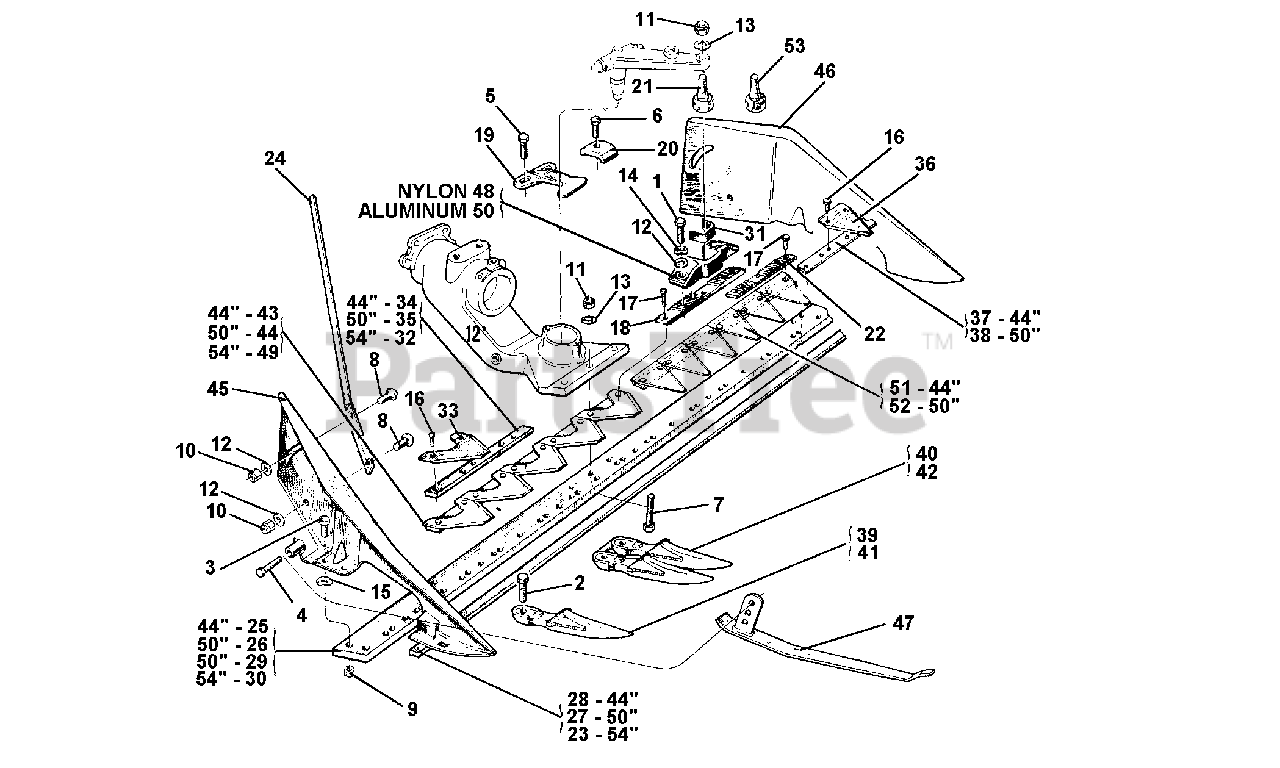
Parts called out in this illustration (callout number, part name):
1	SCREW M8 X 16
2	SCREW TE M10 X 25
3	SCREW TE M10 X 30
4	SCREW TE M10 X 20 UNI 5739-8G
5	SCREW M10 X 30
6	SCREW TE M10 X 35 UNI 5739-8G
10	NUT, SELF LOCKING M8
11	SELF LOCKING NUT
12	WASHER, FLAT 8.4
13	SUPER WASHER 10 DIN 6796
14	WASHER, LOCK 8.4
15	WASHER, LOCK 10.5
16	RIVET 5.3 X 14
17	RIVET TSV 5.3 X 14
18	SUPPORT, BLADE CONNECTION
19	HOLDER, BLADE, DOUBLE
20	HOLDER, STRIP
21	BLADE CONTROL PIN
22	BLADE PLATE
23	19 SECTIONS BLADE GUIDE
25	BAR, CENTRAL, 1.10
26	BAR, CENTRAL, 1.27
27	GUIDE, BLADE L 1270
28	GUIDE, BLADE, 15 SECTIONS
29	HEAVY FRONT BAR 1.27 MT.
30	FRONT BAR 1.40 MT.
32	STRIP, FOR 19-SECTION BLADE
33	SECTION, SCORED BLADE
34	STRIP, 15 SEC. BLADE
35	STRIP, 17 SEC. BLADE
36	INDIVIDUAL BLADE, NA
37	STRIP WITH 22 SECTIONS
38	STRIP WITH 25 SECTIONS
39	TOOTH, SINGLE THICK
40	TOOTH, DOUBLE THICK
41	TOOTH, SINGLE MEDIUM THICK
42	TOOTH, DOUBLE MEDIUM THICK
43	BLADE, 15 SECTIONS
44	BLADE, 17 SECTION
48	NYLON BLADE COUPLING
49	BLADE 19 SECTIONS
50	BLADE CONNECTION
51	BLADE WITH 22 NARROW SECTIONS
52	BLADE WITH 25 NARROW SECTIONS
53	BALL BEARING PIN
